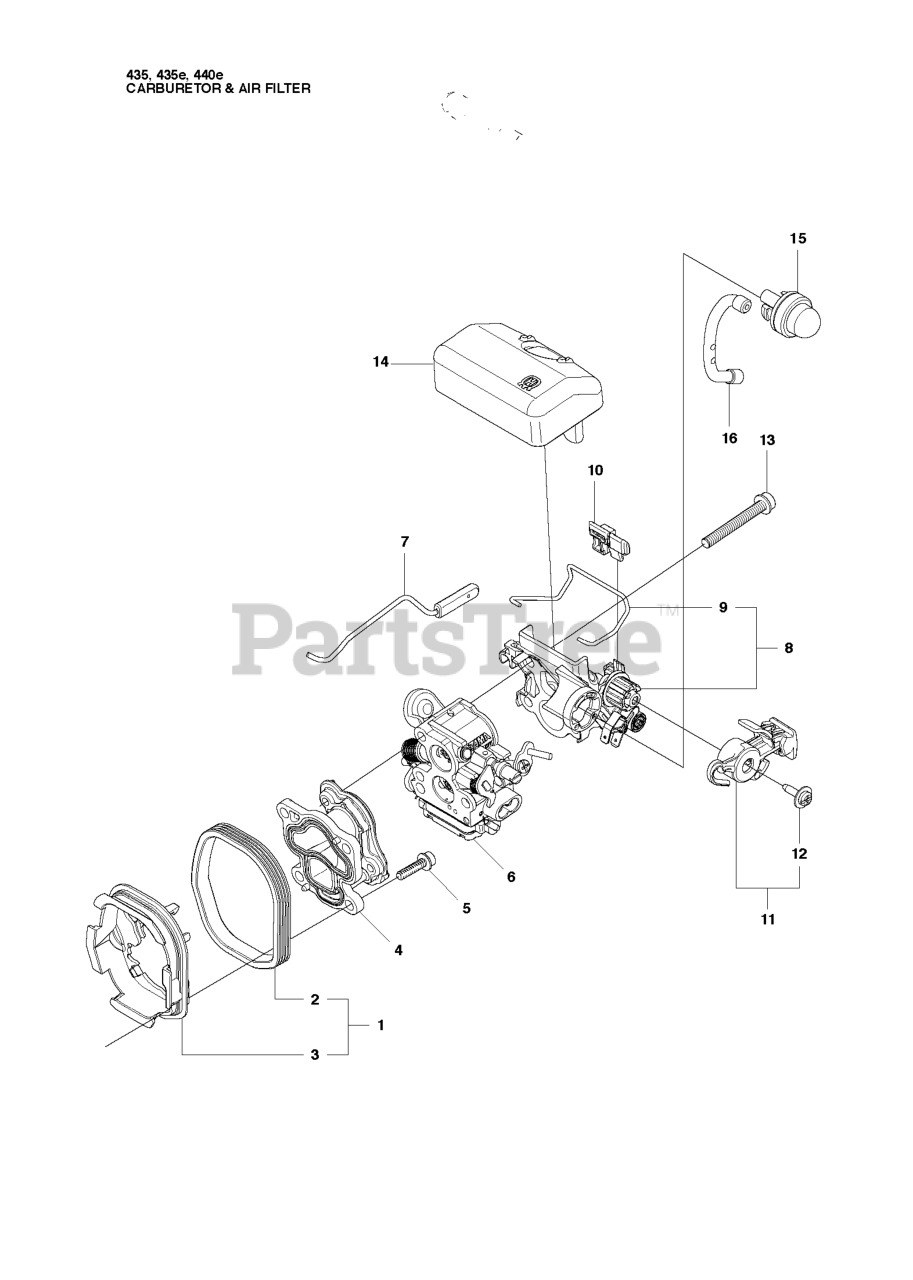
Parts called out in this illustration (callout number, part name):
1	INSULATION WALL
2	INSULATION WALL
3	INSULATION WALL
4	INLET PIPE
6	CARBURETOR
7	THROTTLE ROD ASSY
8	FILTER HOLDER
14	AIR FILTER
15	AIR PURGE BUBBLE
